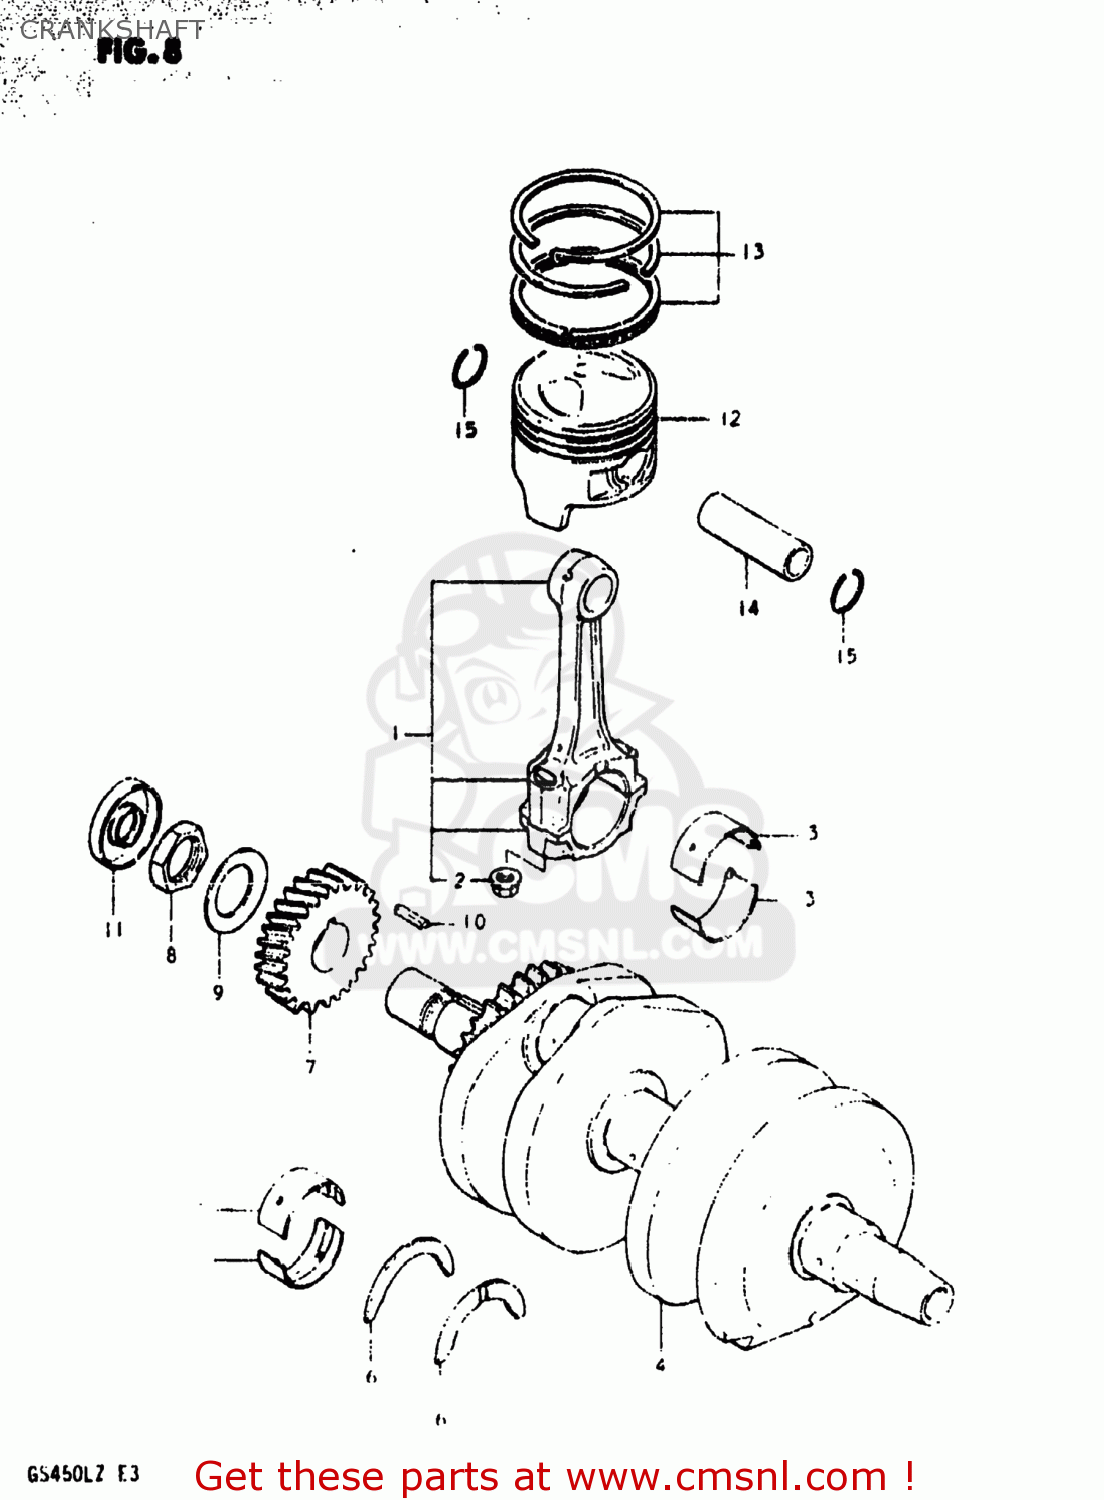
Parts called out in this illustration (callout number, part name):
1	ROD ASSEMBLY,CONNECTING
2	NUT
3	BEARING,CRANK PIN
4	CRANKSHAFT
5	METAL CRANKSHAFT
6	PLATE,CRANK THRUST
7	GEAR,PRIMARY DRIVE NO.28
8	NUT
9	WASHER
10	KEY
11	OIL SEAL
12	PISTON
13	RING SET,PISTON
14	PIN,PISTON (18MM)
15	CIRCLIP
